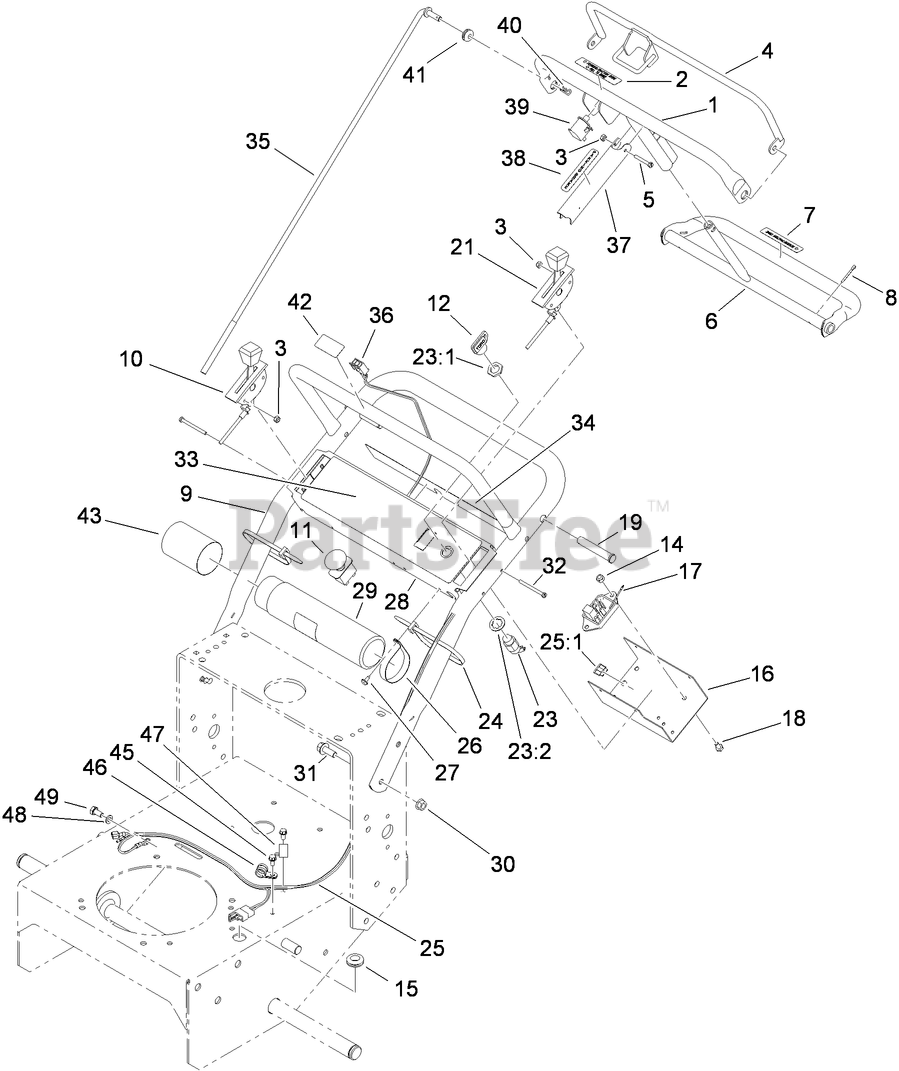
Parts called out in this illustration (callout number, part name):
1	BAR-CONTROL
2	DECAL
3	NUT-LOCK, NI
5	SCREW-SHH
6	PIVOT-CONTROL
7	DECAL
8	PIN-COTTER
9	HANDLE-UPPER
10	CABLE-CHOKE
11	SWITCH-PTO
12	KEY-IGNITION
14	NUT-LOCK, NI
15	GROMMET
16	PANEL-BOTTOM
17	MODULE-DELAY
18	SCREW-HH
19	PIN-CLEVIS
21	CABLE-THROTTLE
23	SWITCH-ON / OFF
23:1	NUT-HH
23:2	WASHER-TOOTH, INTERNAL
24	TIE-CABLE
25	HARNESS-WIRE
25:1	FUSE-BLADE, 7.5 AMP
26	CLAMP-R
27	SCREW-HWHTF
28	PANEL-CONTROL
29	TUBE-MANUAL
30	NUT-HF
31	SCREW-HHF
32	SCREW-SHH
33	DECAL-PANEL, CONTROL
34	DECAL-DANGER
35	ROD-CONTROL
36	CONNECTOR-BODY
37	LEVER-BRAKE, PARKING
38	DECAL-LEVER, PARKING
39	SWITCH-BAIL
40	PIN-COTTER
41	GROMMET-RUBBER
42	DECAL-PROTECTION, EAR
43	CAP-HOUSING
45	SCREW-HWH
46	CLAMP-R
47	CLAMP-CABLE
48	WASHER-LOCK
49	SCREW-HH
